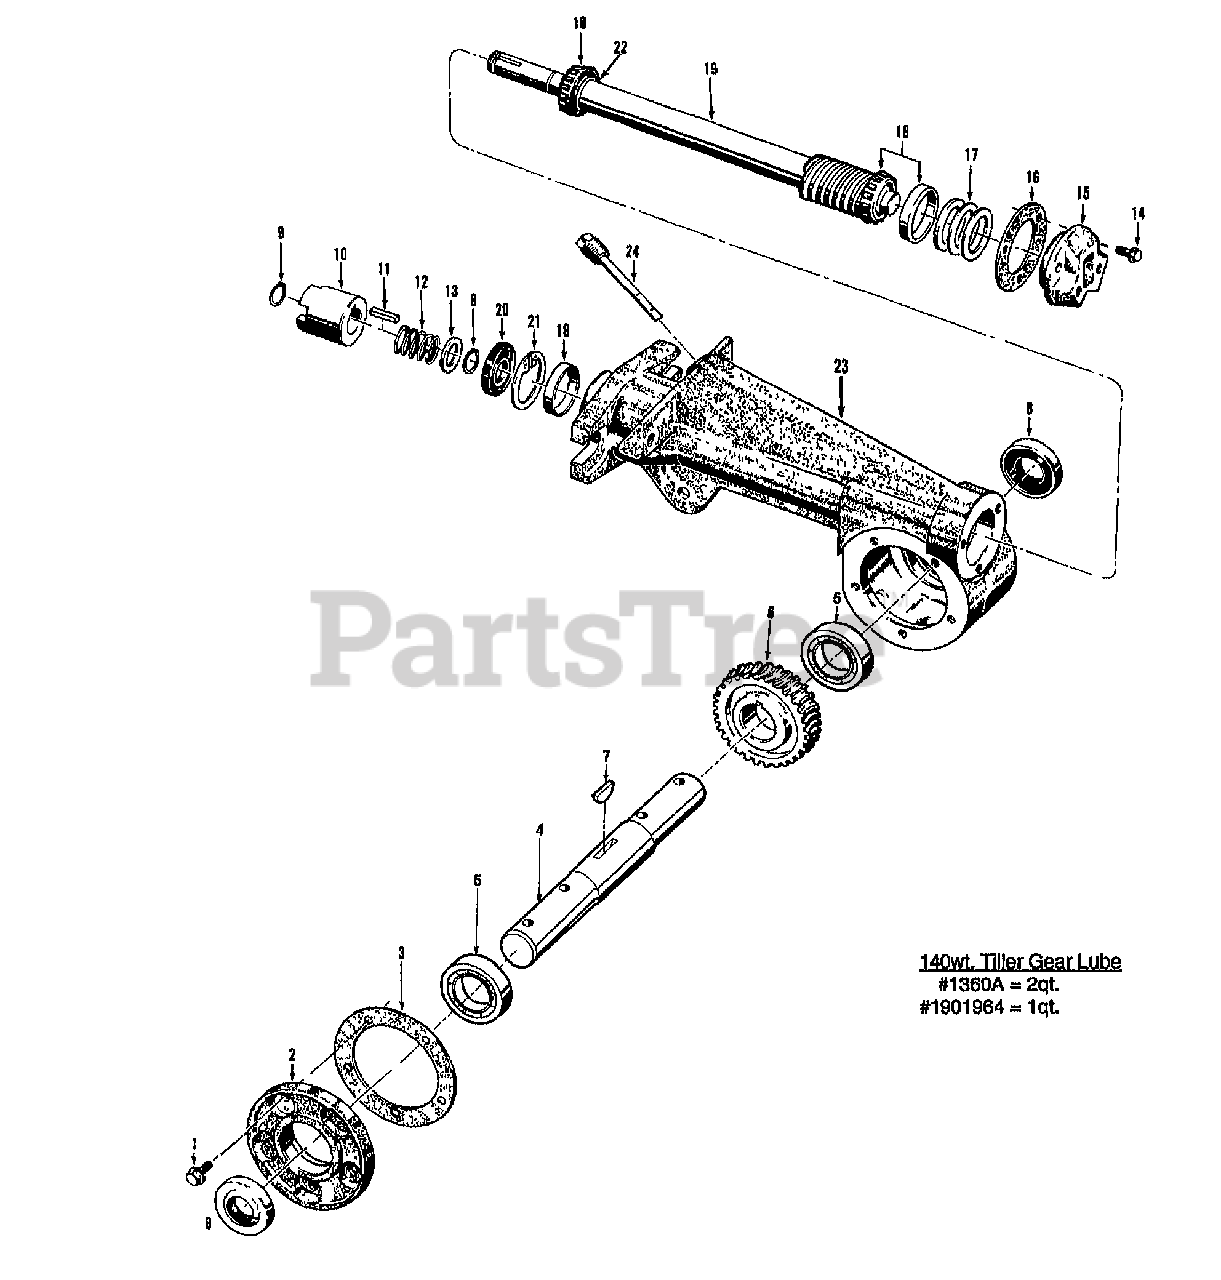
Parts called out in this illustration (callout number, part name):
1	KIT-SEALING SCRS (5)W/LIT
2	COVER-TILLER HSG MACH
3	GASKET-TILLER COVER
4	SHAFT-TILLER MACH HORSE
5	BEARING-BALL
6	GEAR-WORM MACH RTH HORSE
7	KEY-WOODRUFF .25X1.12
8	SEAL-TILLER SHAFT
9	RING-RETAIN EXT .707 ID
10	KIT-CLUTCH DOGS TILLER
10	CLUTCH-DOG HORSE TRANS
11	KEY-.188 SQX1.0
12	SPRING (TC)
13	SHIM-1.0X.7656X.062
14	KIT-SEALING SCRS (3)
15	CAP-REAR #1115
16	GASKET-BRG COVER
17	SHIM-1.75X1.5X.01
17	SHIM-1.75X1.5X.03
17	SHIM-1.75X1.5X.005
17	SHIM-1.75X1.5X.062
18	KIT-BRG CONE&RACE-DRIVESHAFT
19	KIT-TILLER DR SHAFT
20	SEAL-OIL DRIVESHAFT
21	RING-RETAINING 5000-181
22	SHIM-1.0X.7656X.062
23	HOUSING-TILLER W/SLEEVE
24	ASSM-DIPSTICK HORSE TRANS
